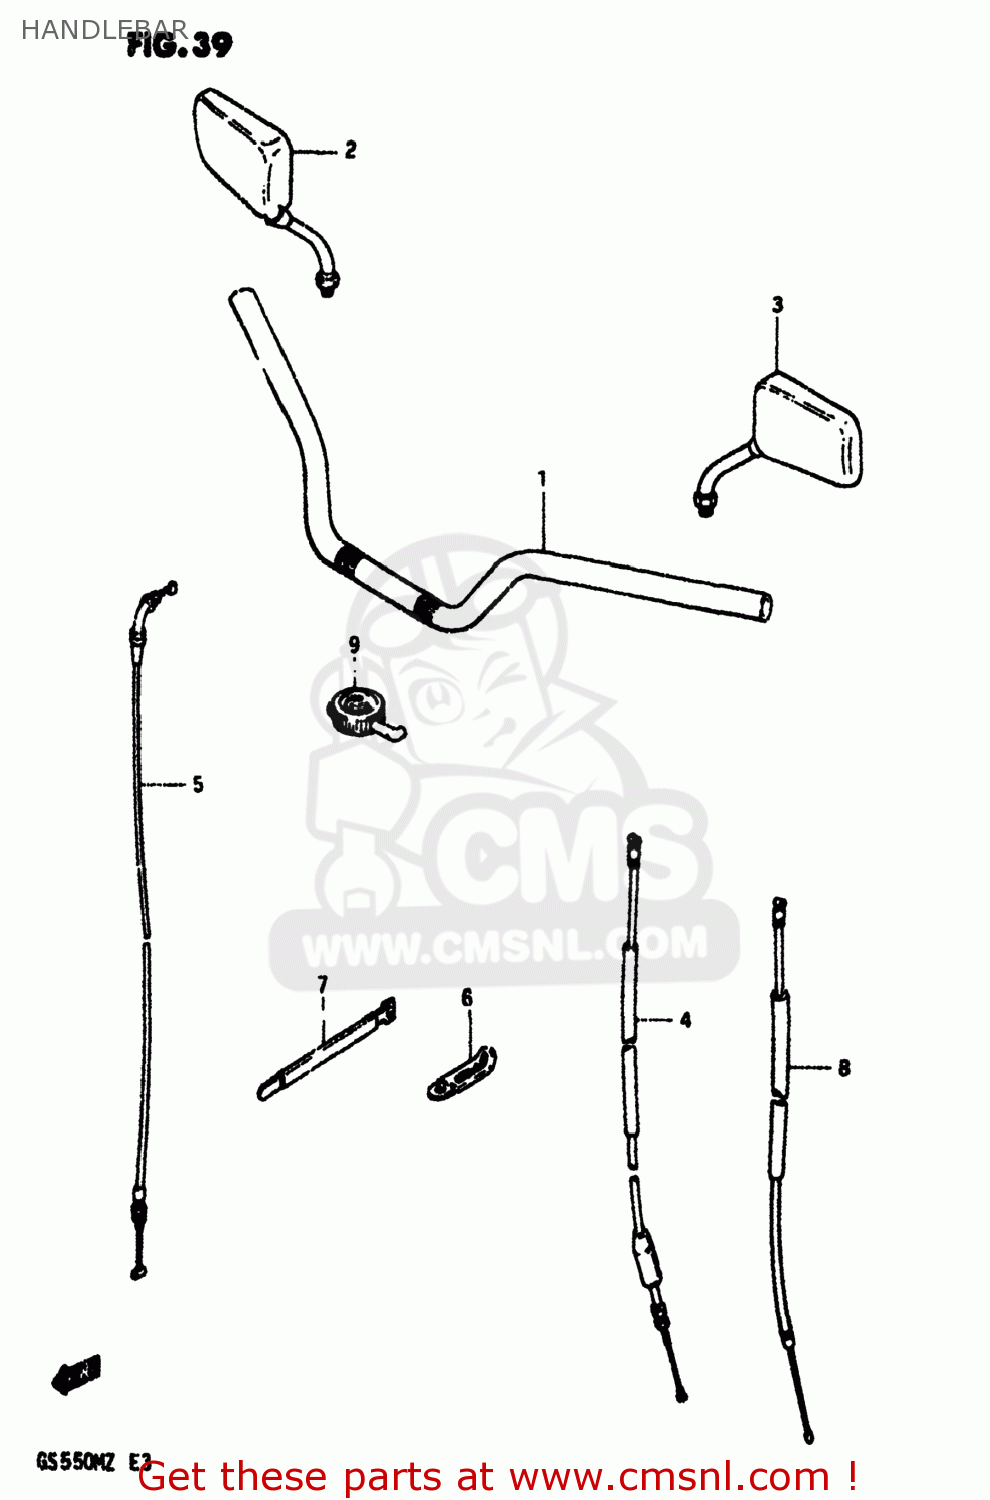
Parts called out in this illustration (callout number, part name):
1	HANDLEBAR
2	MIRROR ASSEMBLY,REAR VIEW
3	MIRROR ASSEMBLY,REAR VIEW
4	CABLE ASSY,CLUTCH
5	CABLE ASSEMBLY,THROTTLE
6	CLAMP
7	CLAMP
8	CABLE COMP,STARTER
9	GAUGE ASSY,AIR PRESSURE
